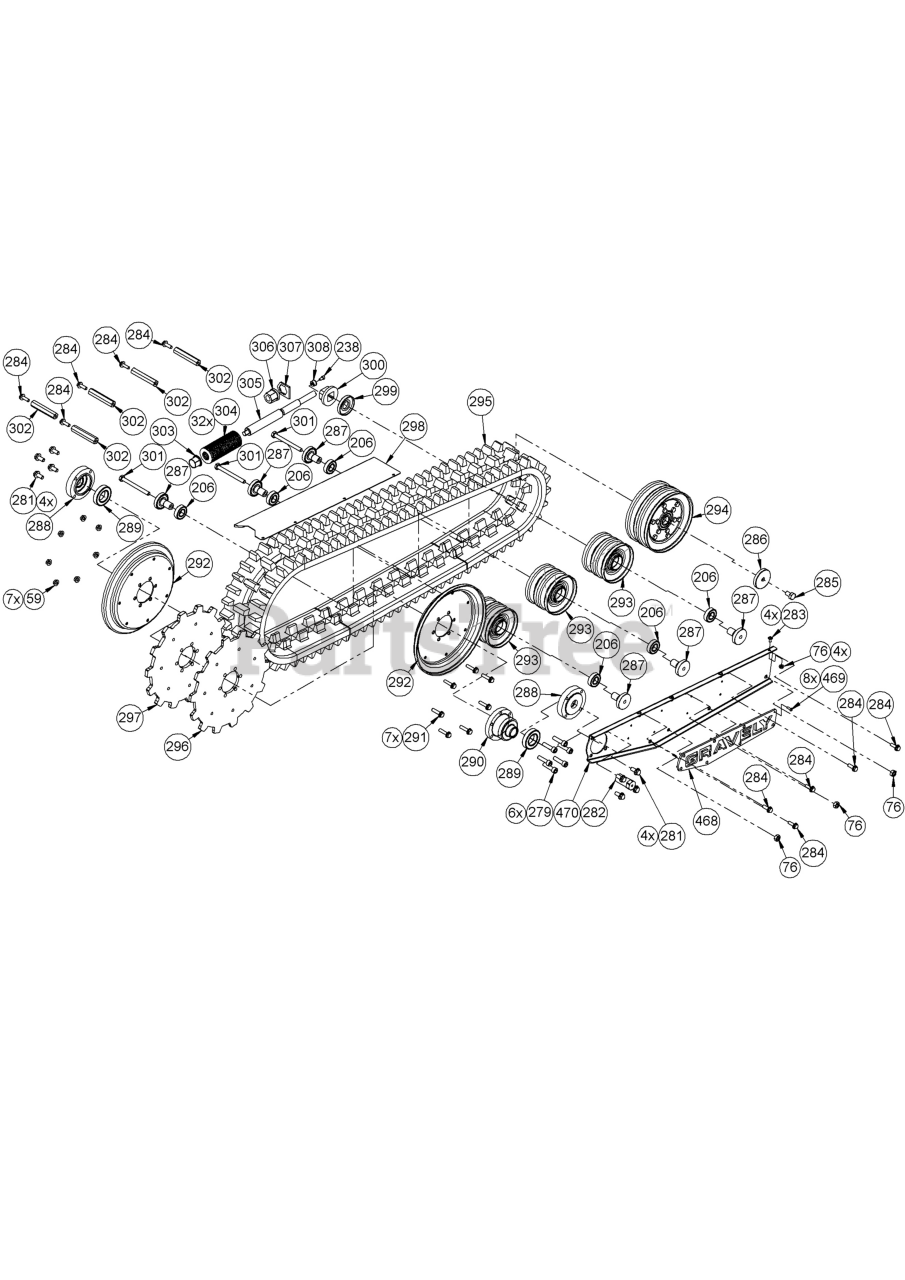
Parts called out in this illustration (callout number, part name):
59	NUT, FLG SLF LK M8 CL 8 ZCC
76	NUT, HEX M10 DIN 934 8 ZCC
206	BRG,BALL .6004-2RSH (20X42X12)
238	SCR, SKH M6X12 DIN ISO 4762 8.8
279	SCR, SKH M10X40 DIN ISO 4762 8.8
281	BLT, SER FLG M10X22 VERBUS RIPP ZIL.
282	NUT, AXLE
283	TORX FBHCS M6X12 8.8
284	BLT, SER FLG M8X25 VERBUS RIPP 100
285	BLT, HEX M12X20 DIN 933 8.8 ZCC
286	COVER, BEARING (OUTSIDE)
287	BUSHING, SLEEVE
288	SHIELD, BEARING
289	BRG,BALL .6007-2RS DIN625(35X62X14)
290	HUB, SPROCKET
291	BLT, SER FLG M8X35 VERBUS RIPP BK
292	HALF, SPROCKET PULLEY
293	ROLLER, TRACK
294	ASSY, IDLER WHEEL
295	TRACK, RUBBER
296	HALF, SPROCKET (8)
297	HALF, SPROCKET (10)
298	COVER, ROLLER GUIDE (RH)
299	COVER, BEARING (INSIDE)
300	BUSHING, AXLE
301	BLT, HEX M10X11 DIN 931 8.8 ZCC
302	NUT, COUPLING
303	BSHG, DU FLG BB2521DU
304	WSHR, BLVL A50X25.4X3 DIN 2093
305	SHAFT, TENSION
306	NUT, FLG M20 DIN 6331 ZCC
307	INDEXER, THRUST BUSHING
308	BUSHING, THRUST
468	SIGN, GRAVELY (RH)
469	RVT, 4.8X16.9 ST ZCC
470	SHIELD, ROLLER GUIDE (RH)
